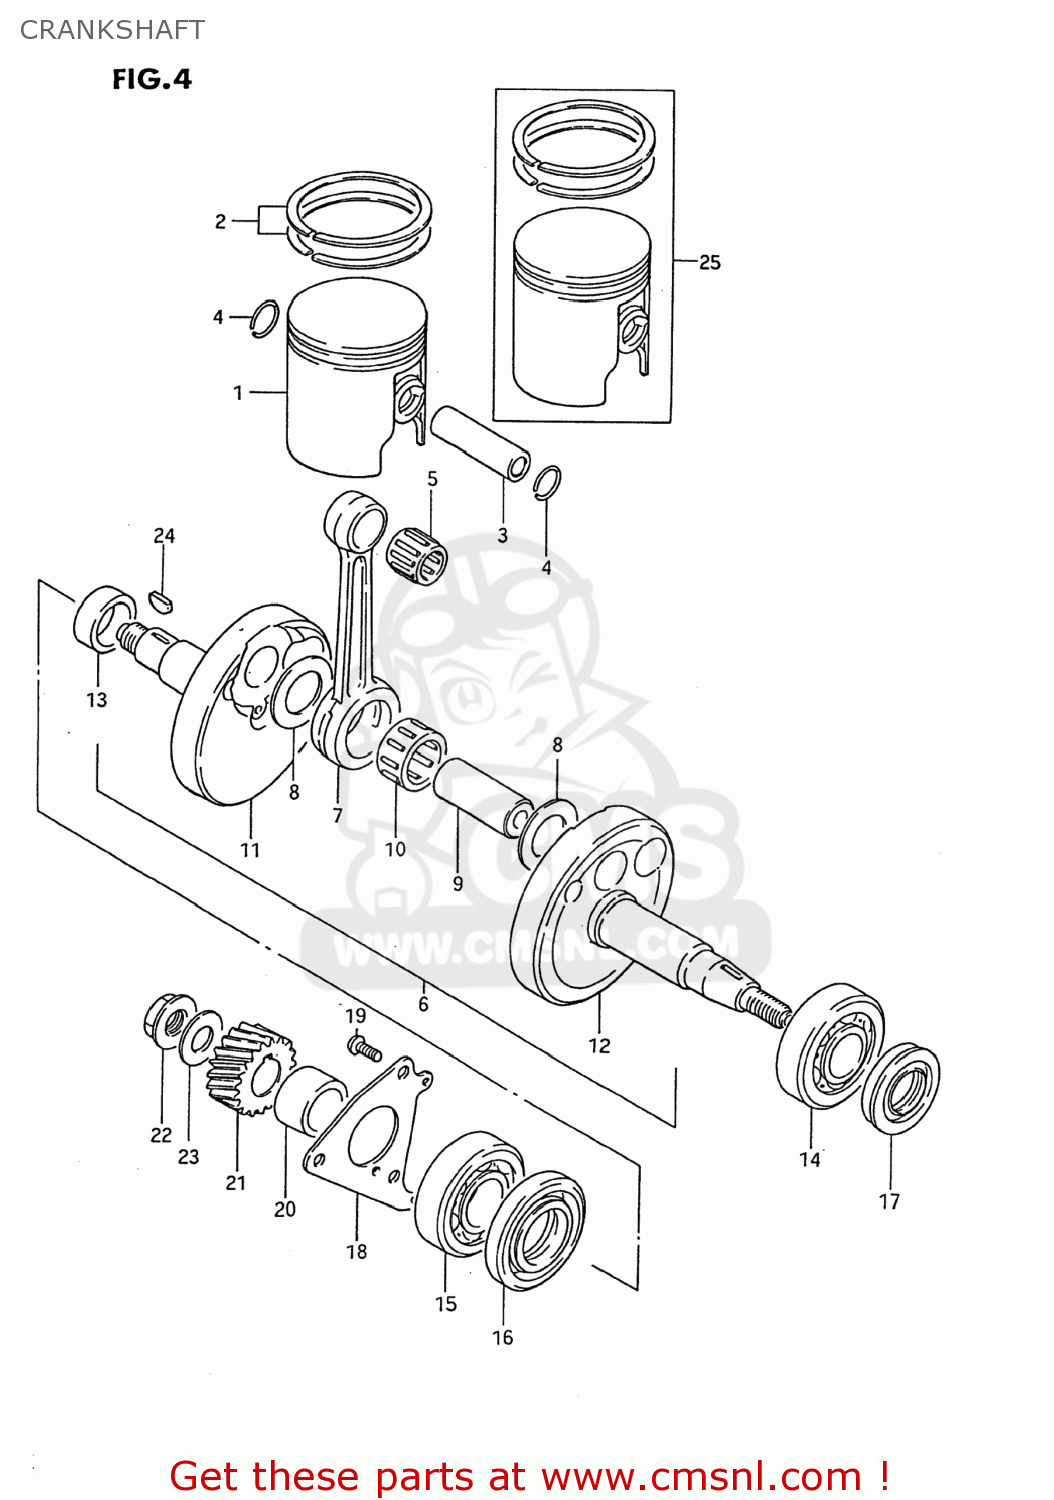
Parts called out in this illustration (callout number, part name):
1	PISTON (49.00MM)
2	PISTON RING SET STD
3	PIN,PISTON
4	RING,SNAP
5	ROLLER BEARING (12X16X1
6	CRANKSHAFT ASSY
7	ROD,CONNECTING
8	WASHER(17X29X1)
9	PIN,CRANK
10	BEARING(17X23X14)
11	CRANKSHAFT,RIGHT
12	CRANKSHAFT,L
13	SPACER(20X26X9)
14	BEARING(20X47X14)
15	BEARING(20X47X14)
16	SEAL,OIL(26X47X7.3)
17	SEAL,OIL(19.6X37X8)
18	RETAINER,CRANKSHAFT BEARING,R
19	SCREW
20	SPACER(20X26X14)
21	GEAR,PRIMARY DRIVE NO.19
22	NUT
23	WASHER
24	KEY
25	PISTON SET (OS:0.5)
